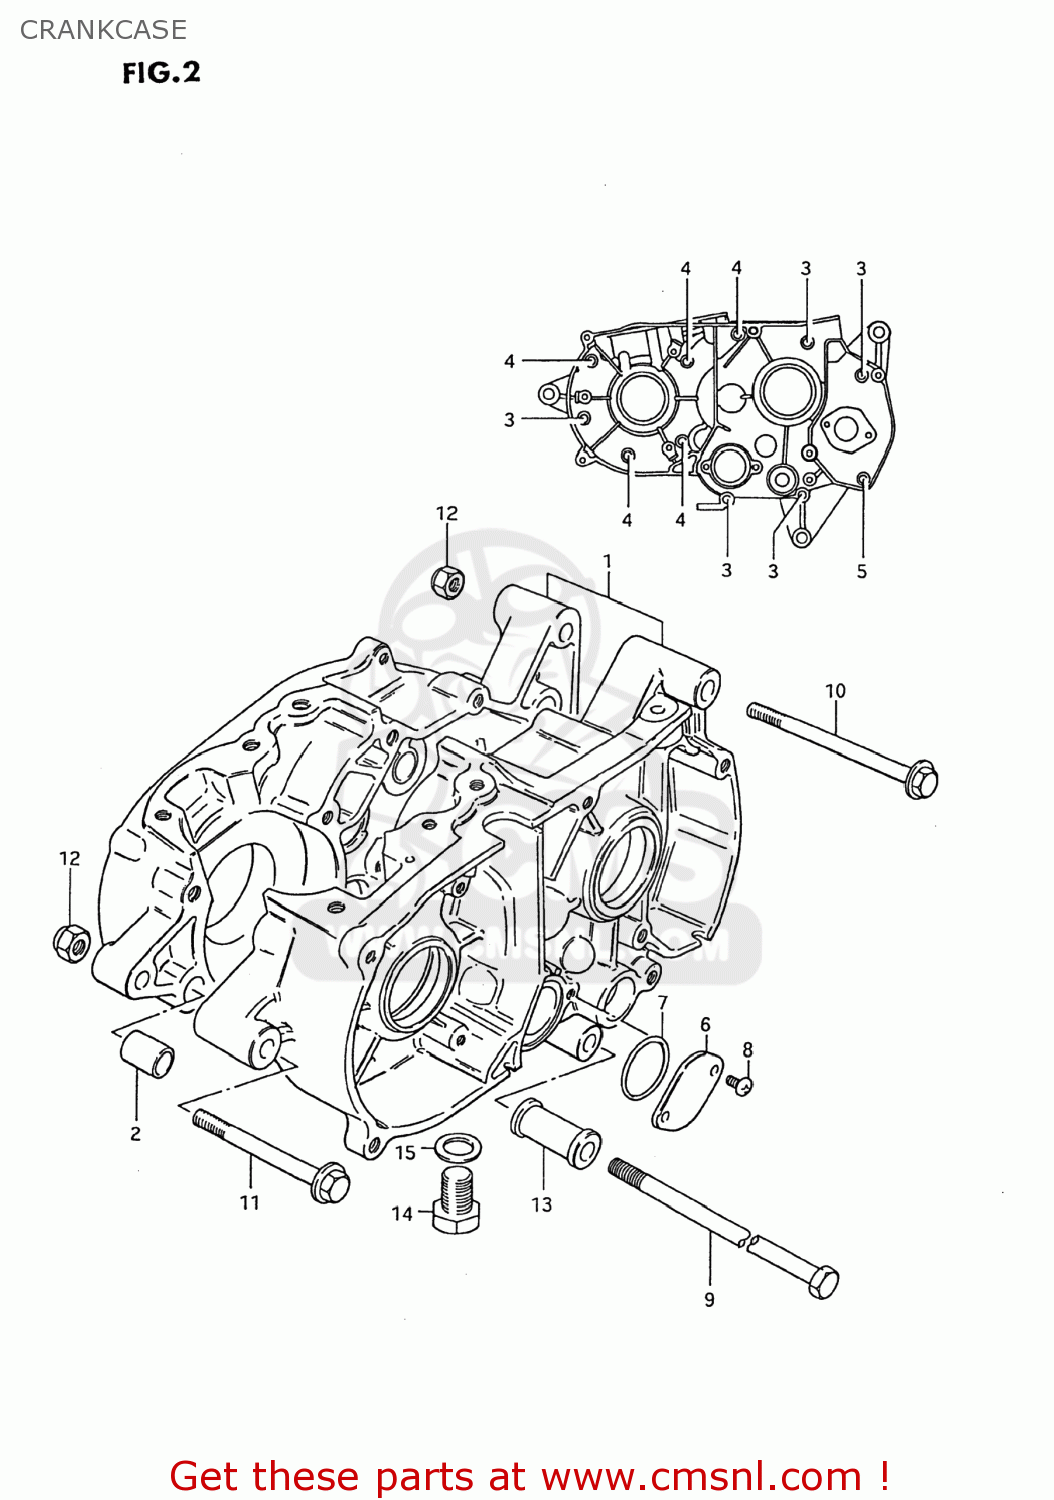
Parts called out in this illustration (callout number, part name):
1	CRANKCASE ASSEMBLY
2	PIN
3	SCREW
4	SCREW
5	SCREW
6	CAP,GEAR SHIFT CAM PIVOT
7	O-RING (D:2.4 ID:26.2)
8	SCREW
9	BOLT(8X230)
10	BOLT(8X100)
11	BOLT(8X70)
12	NUT
13	SPACER,ENGINE MOUNT(L:46)
14	BOLT
15	GASKET(10X14X3.6) (NAS)
